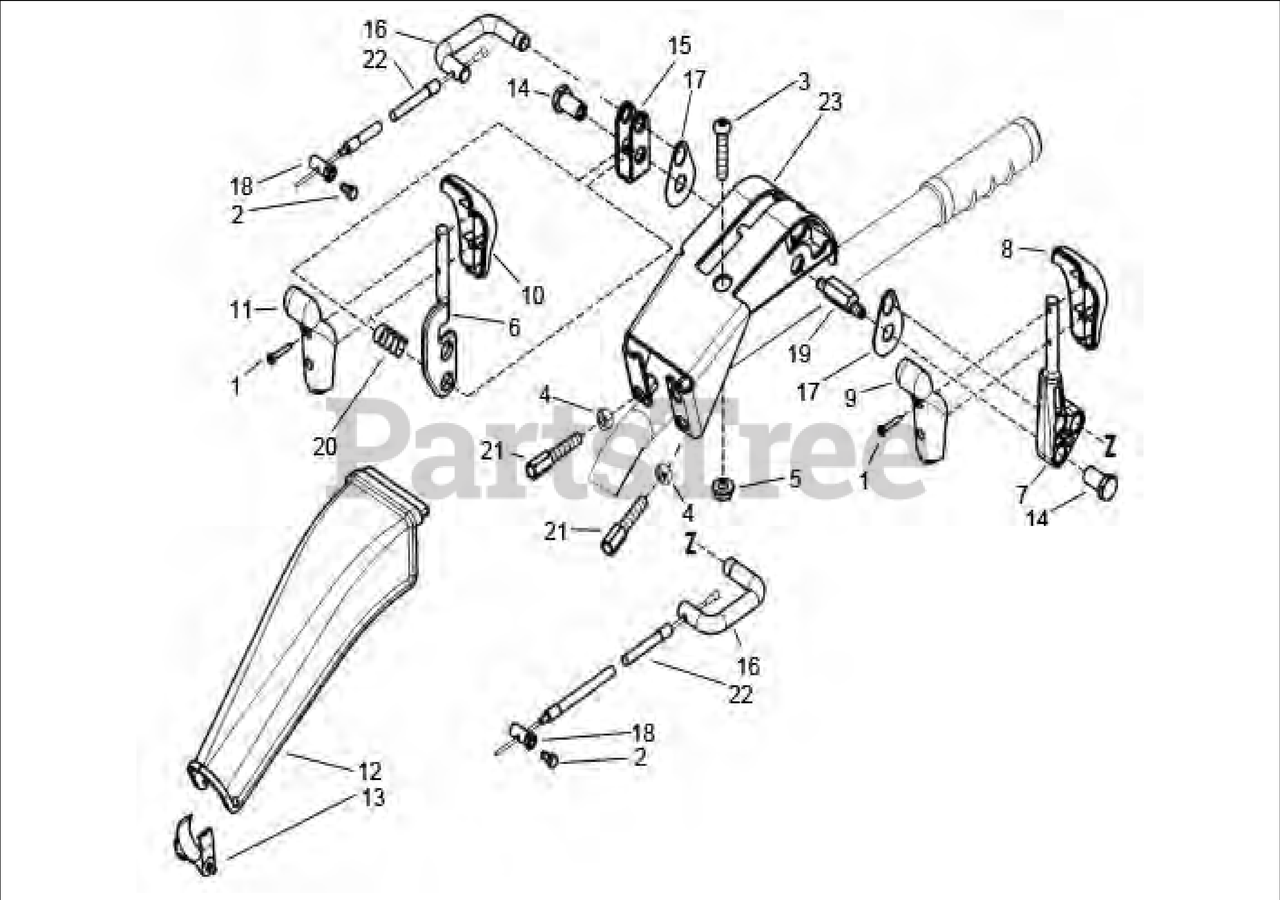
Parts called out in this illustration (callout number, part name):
1	SCREW M5X6
2	CAP SCREW, M6X16
3	SCREW
4	NUT, M8
5	NUT, SELF LOCKING M8
6	LEVER REVERSE
7	LEVER DIFFERENTIAL
8	GRIP UPPER BLACK
9	GRIP LOWER BLACK
10	GRIP UPPER RED
11	GRIP LOWER RED
12	COVER
13	CROSS PIECE
14	BUSHING, REVERSE LEVER
16	ANCHOR PIN
17	PLATE, SMALL
18	CLAMP, CABLE (Cap Screw not included)
20	SPRING
21	CABLE ADJUSTER
22	CABLE ( REVERSE / DIFFERENTIAL)
23	SUPPORT BRACKET
